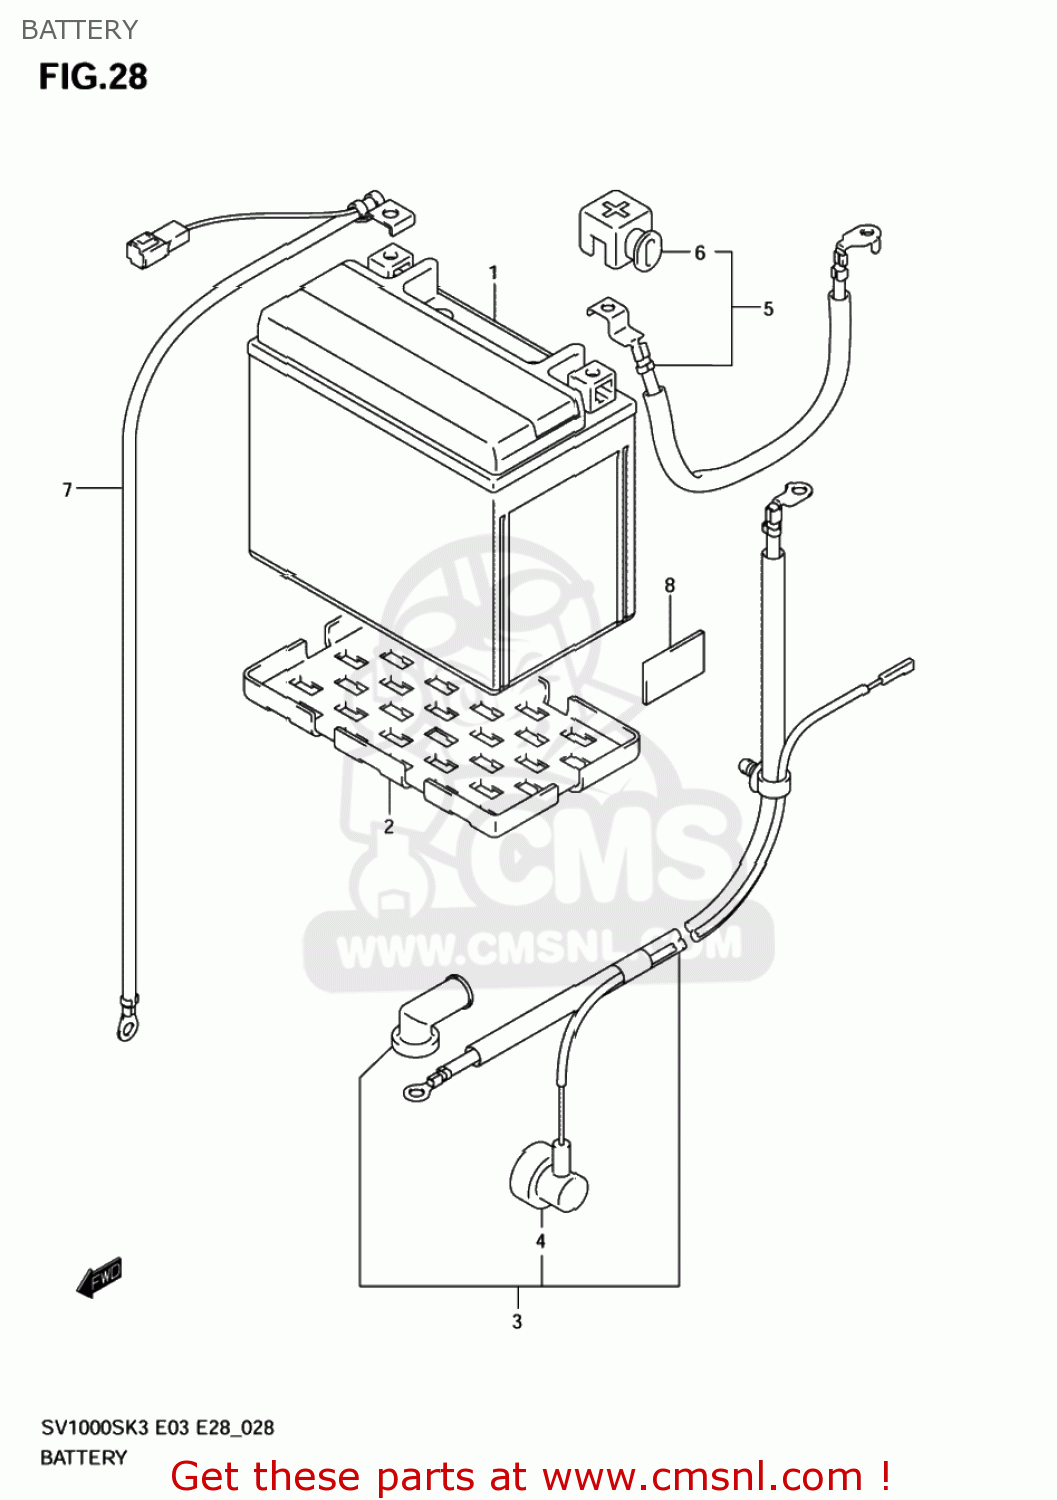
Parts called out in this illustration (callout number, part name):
1	BATTERY ASSY (12V) YTX14-BS
2	PROTECTOR,BATTERY
3	WIRE,STARTER MOTOR LEAD
4	CAP,OIL PRESSURE SWITCH
5	WIRE,BATTERY PLUS LEAD
6	CAP,BATTERY PLUS
7	WIRE,BATTERY M
8	PROTECTOR(30X50X3)
